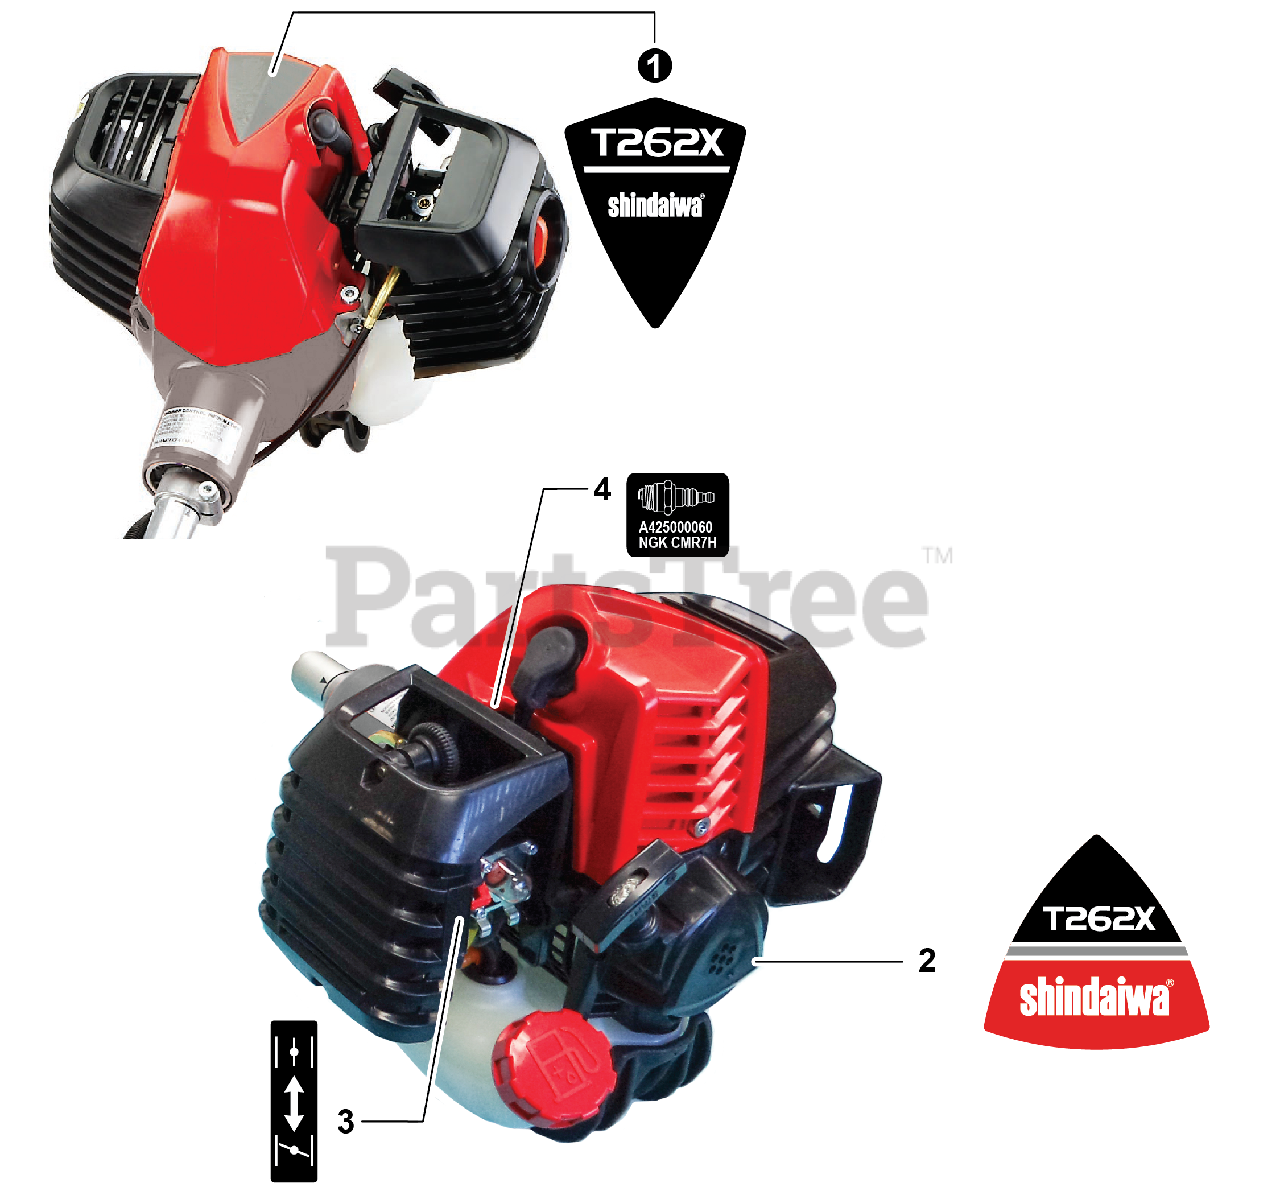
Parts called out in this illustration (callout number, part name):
1	LABEL - MODEL T262X
2	LABEL, RECOIL STARTER
3	LABEL, CHOKE
4	LABEL, SPARK PLUG - CMR7H
